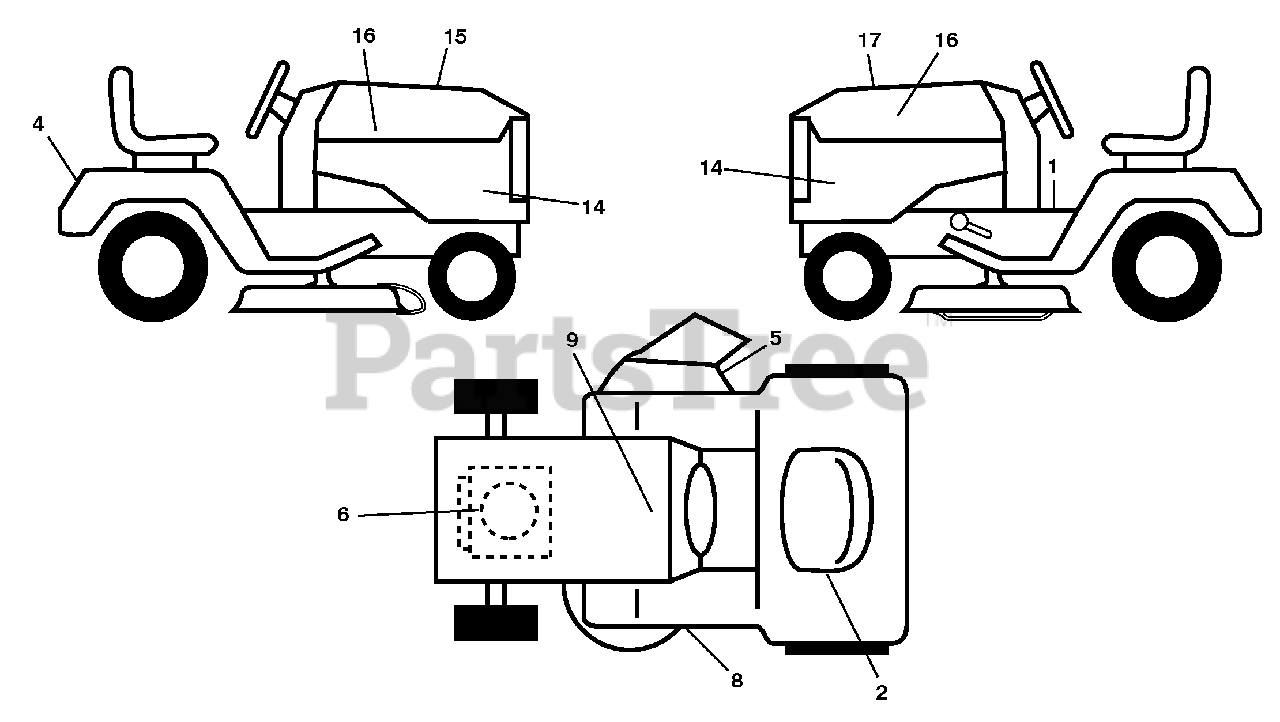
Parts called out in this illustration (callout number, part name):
1	Decal, Operator's
2	Decal, Ethanol E85
4	Decal, Fender
5	Decal, Caution
6	Decal, Eng. HP
8	Decal, Mower Sch.
9	Decal, Battery Dnge/Poi
14	Decal, Panel Side
15	Decal, Cust. Resp.
16	Decal, Hood Logo
17	Decal, Replacement
